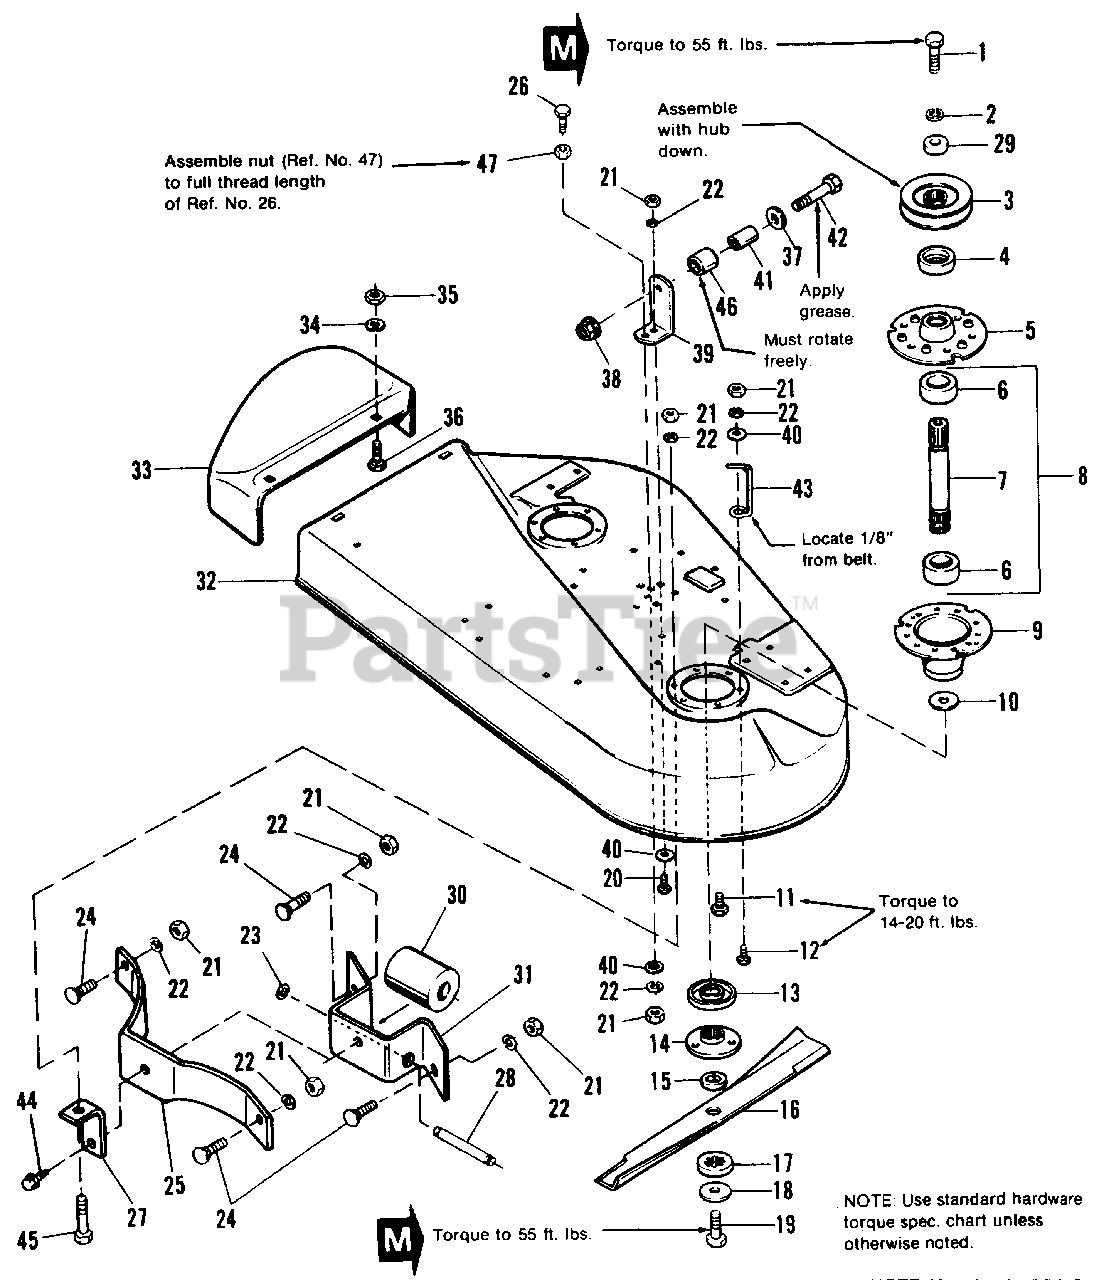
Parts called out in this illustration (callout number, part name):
1	CAPSCREW, Hex, 7/16-14 x 1-1/2
2	LOCKWASHER, 7/16
3	DRIVE PULLEY ASSY.
4	SHIELD, Bearing Upper, Arbor
5	HOUSING, Top
8	SHAFT & BEARING ASSY. (Incl. Ref. Nos. 6, 7 & 15)
9	HOUSING, Bottom
10	WASHER, Shim
11	SCREW, Taptite, 5/16-18 x 5/8
12	SCREW, Taptite, 5/16-18 x 1
13	SHIELD, Lower Grass
14	ADAPTOR, Blade
15	COLLAR, Mower Arbor
17	WASHER, Spline
18	WASHER, Spring
19	CAPSCREW, Hex, 7/16-14 x 1
20	CAPSCREW. Hex, 5/16-18 x 1
21	NUT, Hex, 5/16-18
22	LOCKWASHER, 5/16
23	E-RING
24	BOLT, Carriage. 5/16-18 x 3/4
25	BAFFLE
26	CAPSCREW, Hex Hd., 5/16-18 x 1-1/2
27	BRACKET, Mower
28	SHAFT, Center Roller
29	WASHER, 29/64
30	ROLLER, Small
31	BRACKET, Roller, Center
32	HOUSING, 36"
33	DEFLECTOR
34	LOCKWASHER. 3/8
35	NUT, Hex, 3/8-16
36	BOLT, Carriage, 3/8-16 x 3/4
37	WASHER, Plain
38	LOCKNUT, Hex, Flange, 3/8-16
39	SUPPORT, Up-Stop
40	WASHER, Plain, 5/16
42	CAPSCREW, Hex Hd., 3/8-16 x 1-3/4
44	SCREW, Taptite, 5/16-18 x 1/2
45	CAPSCREW. Hex Hd., 5/16-18 x 1-1/4
47	NUT, Hex, Jam, 5/16-18
